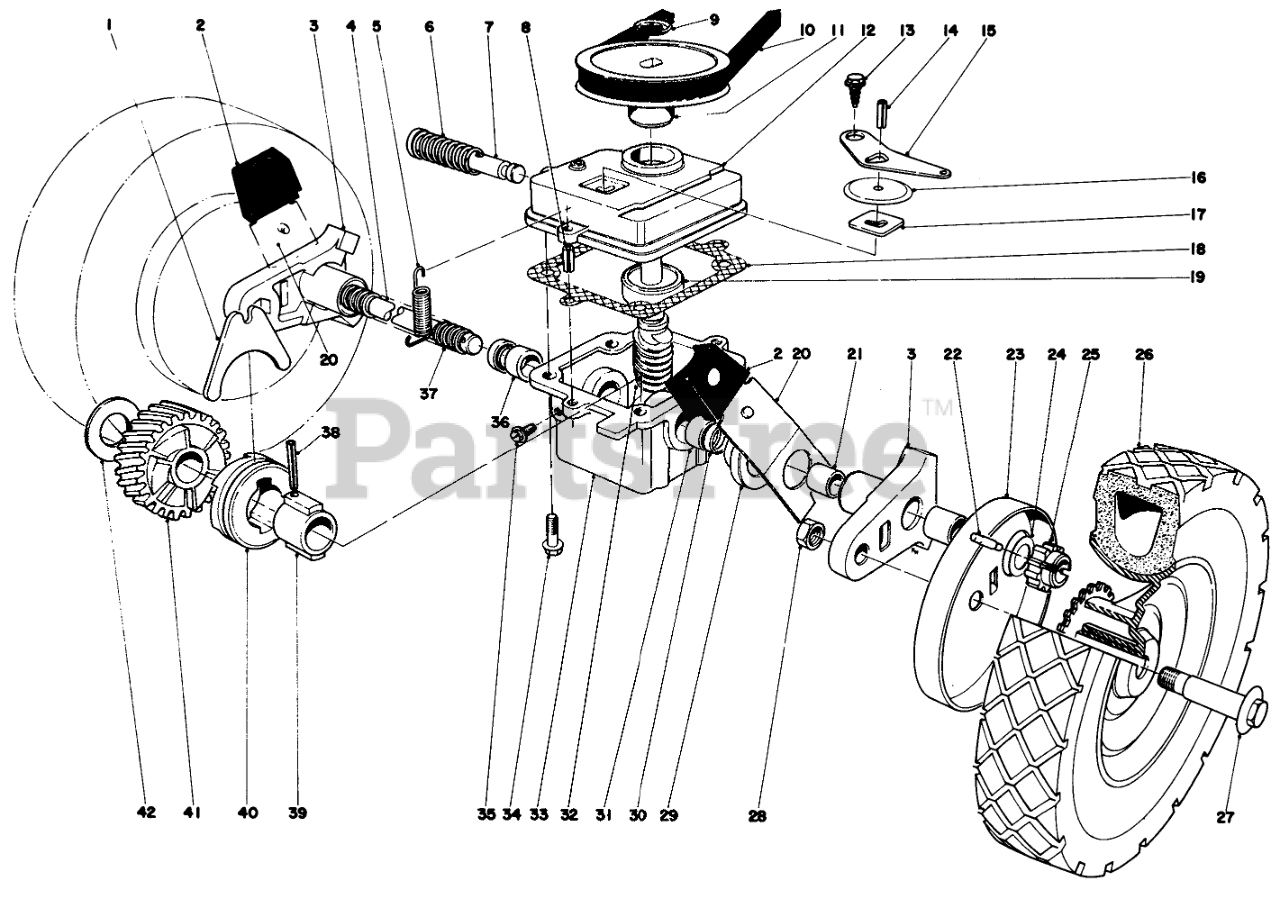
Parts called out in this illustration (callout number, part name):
1	SHIFTER FORK
2	KNOB-ARM
3	Pivot Arm (Incl. Ref. #21)
4	Drive Shaft
5	TENSION SPRING
6	SPRING
7	Shift Rod
8	3/16 X 1/2 ROLL PIN
9	PUSH-ON 93-3236
10	V BELT
11	PULLEY
12	GEAR CASE COVER
13	Screw
14	PIN-ROLL
15	SHIFTER ARM
16	TRANS DUST COVER
17	LATCH PLATE
18	GASKET
19	Bearing
20	SPRING ARM ASM SP
21	BUSHING
22	PIN-GROOVED
23	WHEEL COVER
24	WASHER-THRUST
25	Pinion
26	Wheel & Tire
28	Nut
29	End Cap
30	Seal
31	Bushing
32	Worm Shaft & Gear (Incl. Ref. #41)
33	Gear Case (Incl. Ref. #30-31 & 35-36)
34	Screw
35	NYLON SCREW
36	Bushing
37	COVER-SHAFT, DRIVE
38	COIL PIN
39	SLEEVE
40	CLUTCH JAW
41	Helical Gear
42	THRUST WASHER
